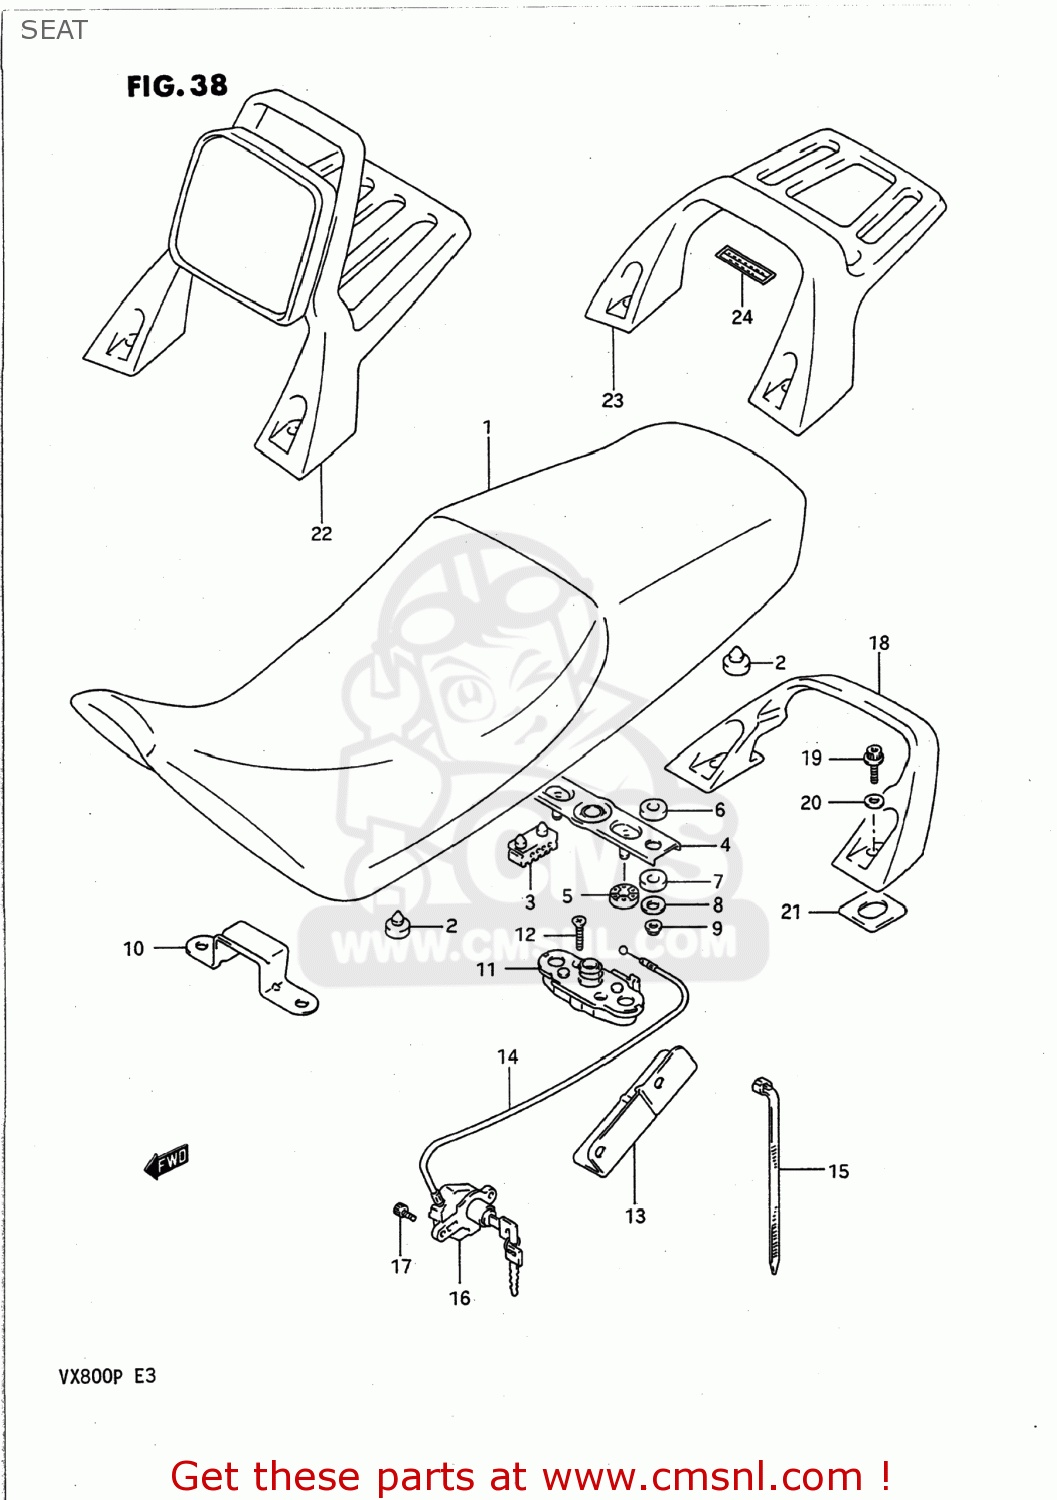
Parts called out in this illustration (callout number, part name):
1	SEAT ASSEMBLY
2	CUSHION
3	CUSHION,SEAT(40X20X15)
4	STRIKER,SEAT LOCK
5	CUSHION,SEAT LOCK(10X22X6)
6	CUSHION,UPR
7	CUSHION,LWR
8	WASHER
9	NUT
10	PLATE,SEAT FR HOOK
11	BRACKET,SEAT SUPPORT,RIGHT
12	SCREW
13	PLATE,SEAT LOCK CABLE
14	CABLE,SEAT LOCK
15	CLAMP(L:165)
16	LOCK SET,SEAT
17	BOLT
18	HANDLE,PILLION RIDER
19	BOLT
20	WASHER 10MM
21	CUSHION,FRAME COVER
22	REAR RACK WITH SISSY BAR
23	CARRIER SET,SUPPORT
24	LABEL,WARNING
